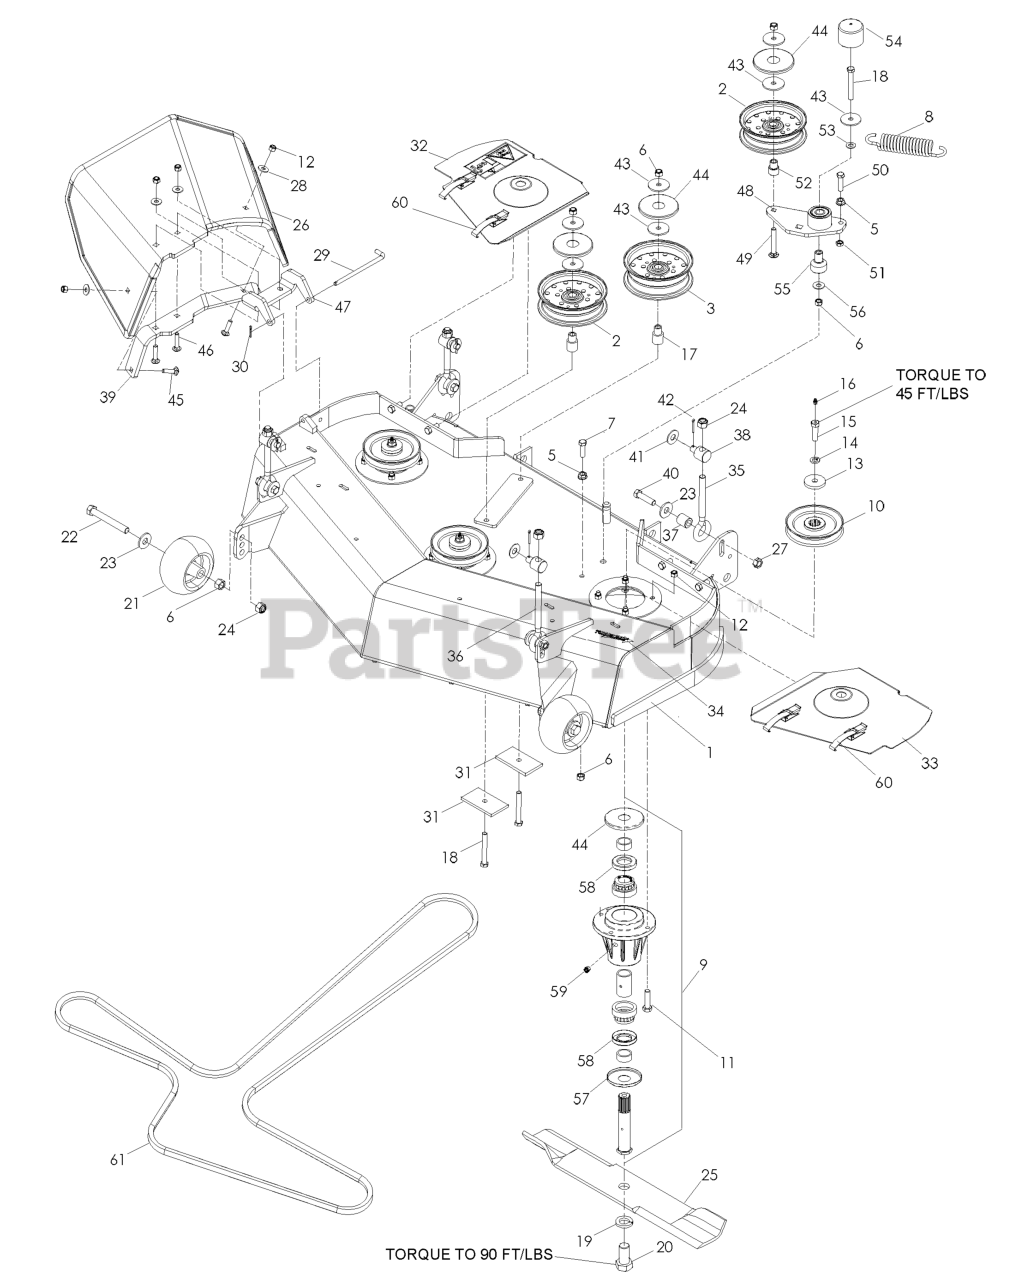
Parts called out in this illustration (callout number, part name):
1	DECK W/DECALS 42"
2	IDLER PULLEY
3	IDLER PULLEY (TALL)
4	NUT HEX 1/2
5	NUT 3/8C WHIZ
6	NUT 3/8-16 NYLOC
7	HCS 3/8C X 1 1/4 GR5
9	HOUSING ASM, 52/61
10	PULLEY 42-48
11	HCS 5/16C X 1 1/4
12	NUT 5/16 NYLOC
13	SPINDLE WASHER
14	WASHER 7/16 LOCK
15	HCS 7/16-20 GD 8 SPEC
16	ZERK
17	IDLER BUSHING
18	HCS 3/8C X 3
19	LOCKWASHER 5/8
20	HCS 5/8F X 1 1/4
21	GAUGE WHEEL
22	HHB, 1/2-13X4
23	WASH USS FLAT 1/2
24	NUT 1/2-13 HEX NYLOC ZD
25	BLADE 14-5/8" TUNNEL RAM
26	CHUTE, RUBBER DISCHARGE 42/48"
27	NUT 7/16C CENTERLOCK
28	WASHER 5/16 FLAT
29	PIN, CHUTE PIVOT
30	RP_COTTER PIN 1/8 X 3/4
31	SUPPORT PLATE
32	BELT SHIELD ASM RH
33	BELT SHIELD ASM LH
34	DECAL, TUNNEL RAM 4"
36	EYEBOLT, 1/2-13 X 5.88
39	BRACKET, REINF-CHUTE
40	HCS 7/16 - 14 X 1 3/4
41	WASHER 1/2 FLAT
42	PIN COTTER 1/8 X 1 ZD
43	WASHER, 3/8 SPEC
44	TOP DUST CAP
45	BOLT, CARRIAGE 5/16X1-1/4
46	RHSNB 5/16-18 X 1-1/2 GR 5 ZD
47	PIVOT BRACKET - RUBBER CHUTE
48	ARM-IDLER W/BRG
49	RHSNB 3/8-16 X 2.75
50	HCS 3/8-16 X 1-1/2
51	NUT 3/8-16 HEX JAM
52	BUSHING, IDLER
53	WASHER 3/8 SAE FLAT
54	CAP, VINYL
55	PIVOT, BEARING
56	WASHER 3/8 FLAT
57	BOTTOM DUST CAP
58	SHAFT SEAL
59	PLUG-VENTED
60	DRAW LATCH
61	DECK BELT
